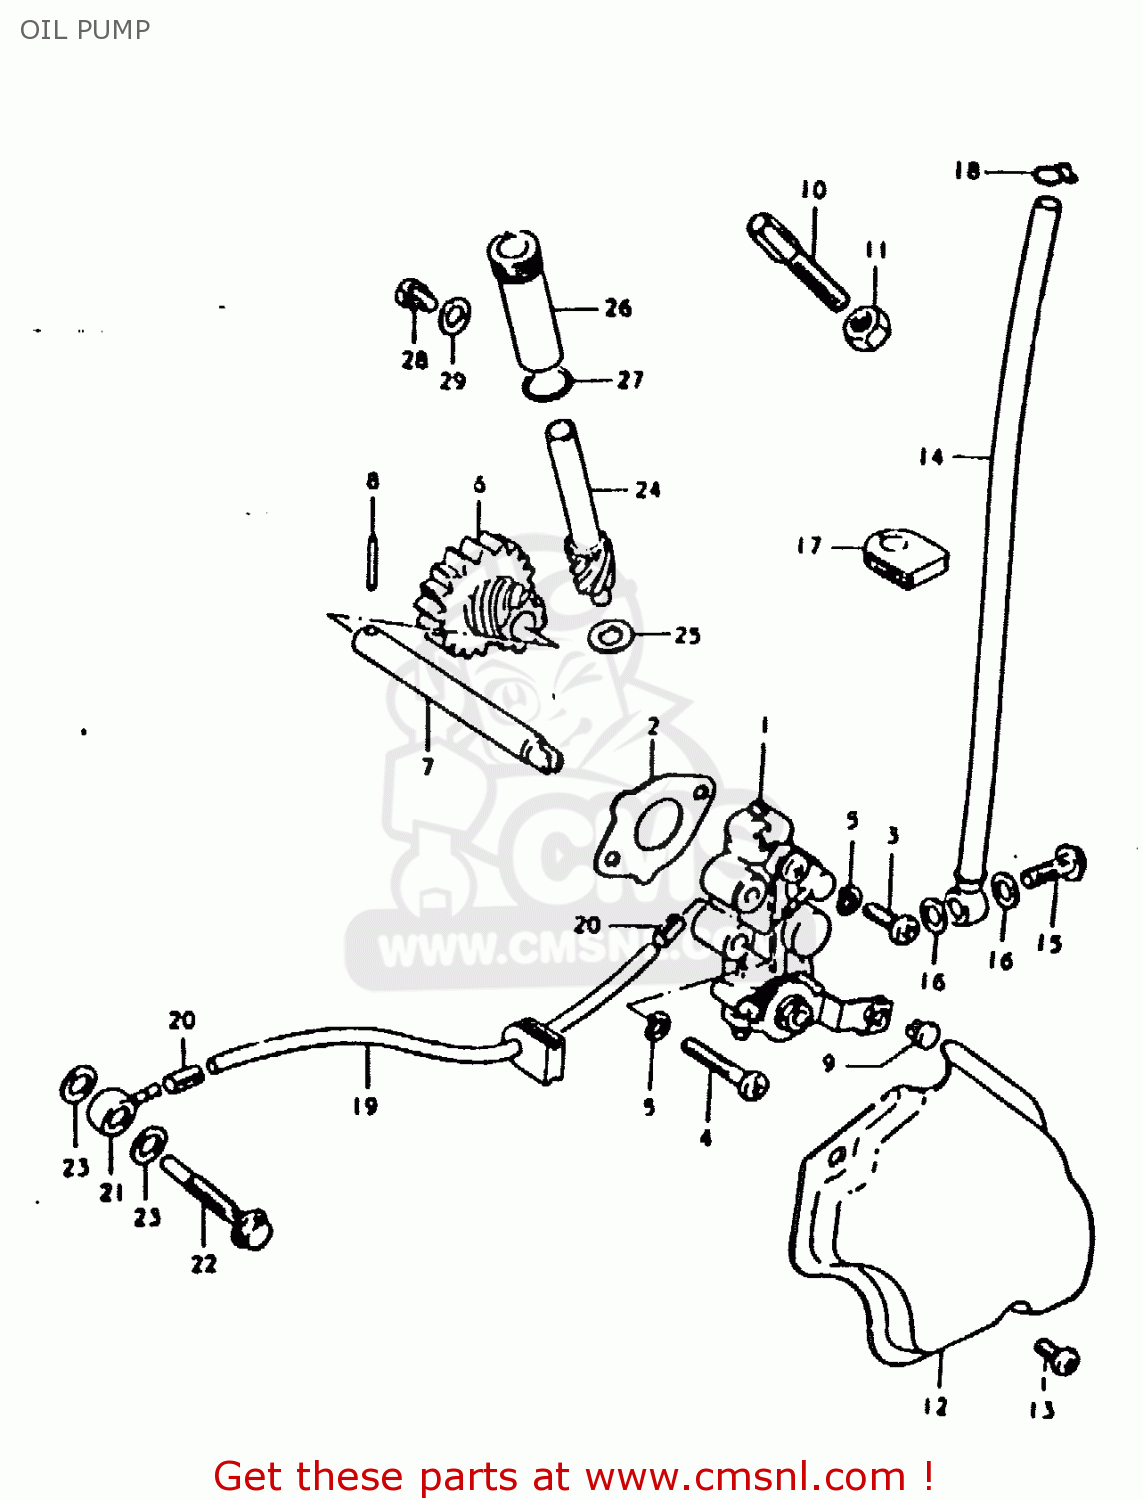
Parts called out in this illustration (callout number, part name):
1	PUMP ASSEMBLY,OIL
2	GASKET,OIL PUMP (NAS)
3	SCREW
4	SCREW
5	LOCK WASHER
6	GEAR,OIL PUMP DRIVE
7	SHAFT,OIL PUMP DRIVE
8	PIN(2.5X19.8)
9	TERMINAL,CABLE
10	BOLT
11	NUT
12	CAP,OIL PUMP INSPECTION
13	SCREW
14	HOSE,OIL NO.1
15	UNION BOLT
16	GASKET(6.2X11X1).2 (NAS)
17	GROMMET
18	CLIP
19	HOSE,OIL NO.2
20	CLIP
21	UNION
22	UNION
23	GASKET(6.2X11X1).2 (NAS)
24	GEAR,TACHOMETER DRIVEN(NT:10)
25	WASHER(8X13.7X1)
26	SLEEVE,TACHOMETER DRIVE GEAR
27	O RING(D:1.3,ID:9.6)
28	BOLT
29	WASHER
